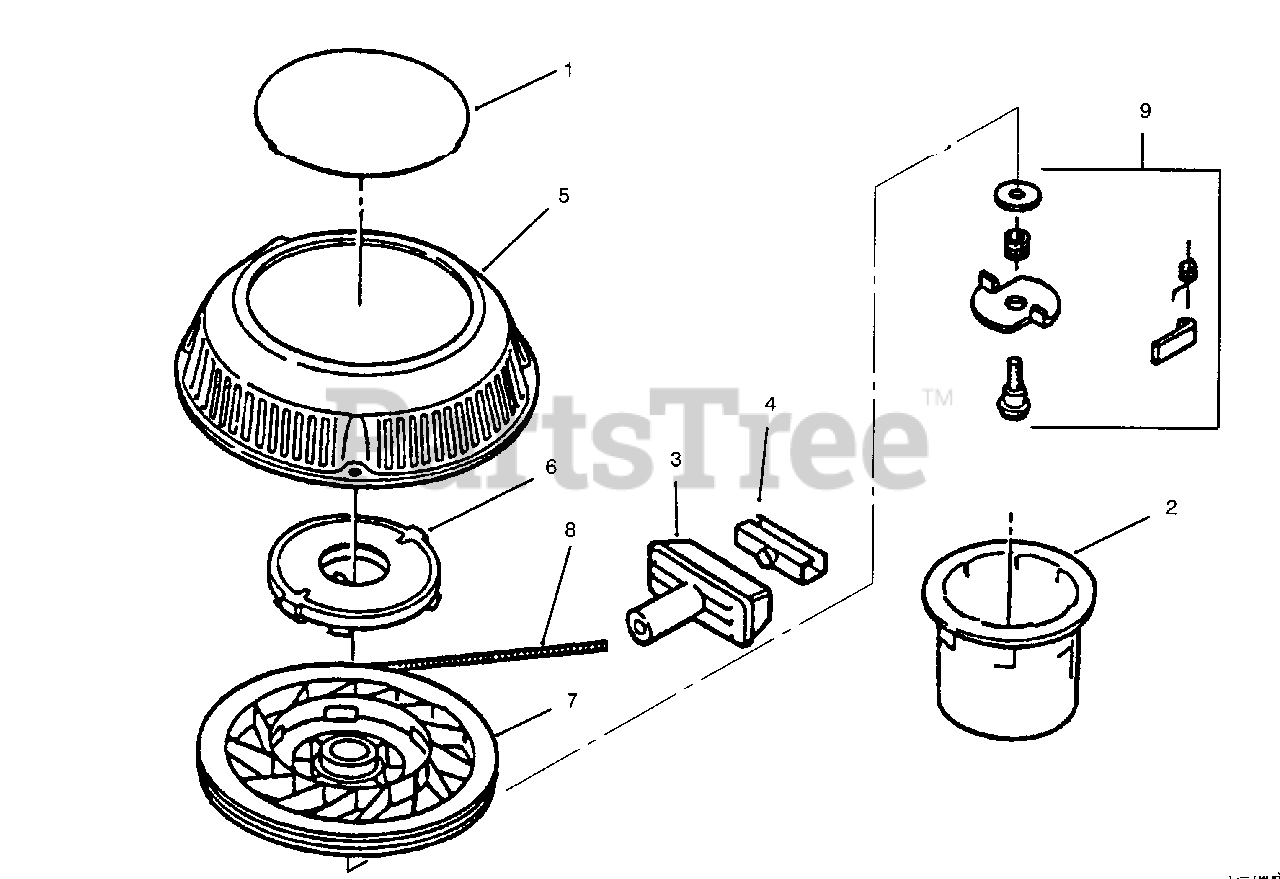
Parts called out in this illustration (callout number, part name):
1	Decal-Model No.10590
1	Decal-Model No.10591
2	Hub-Starter
3	Handle-Starter
4	Insert-Clip, Rope
5	Housing-Starter
6	Recoil Spring & Keeper
8	Rope
9	Assembly-Dog Kit
